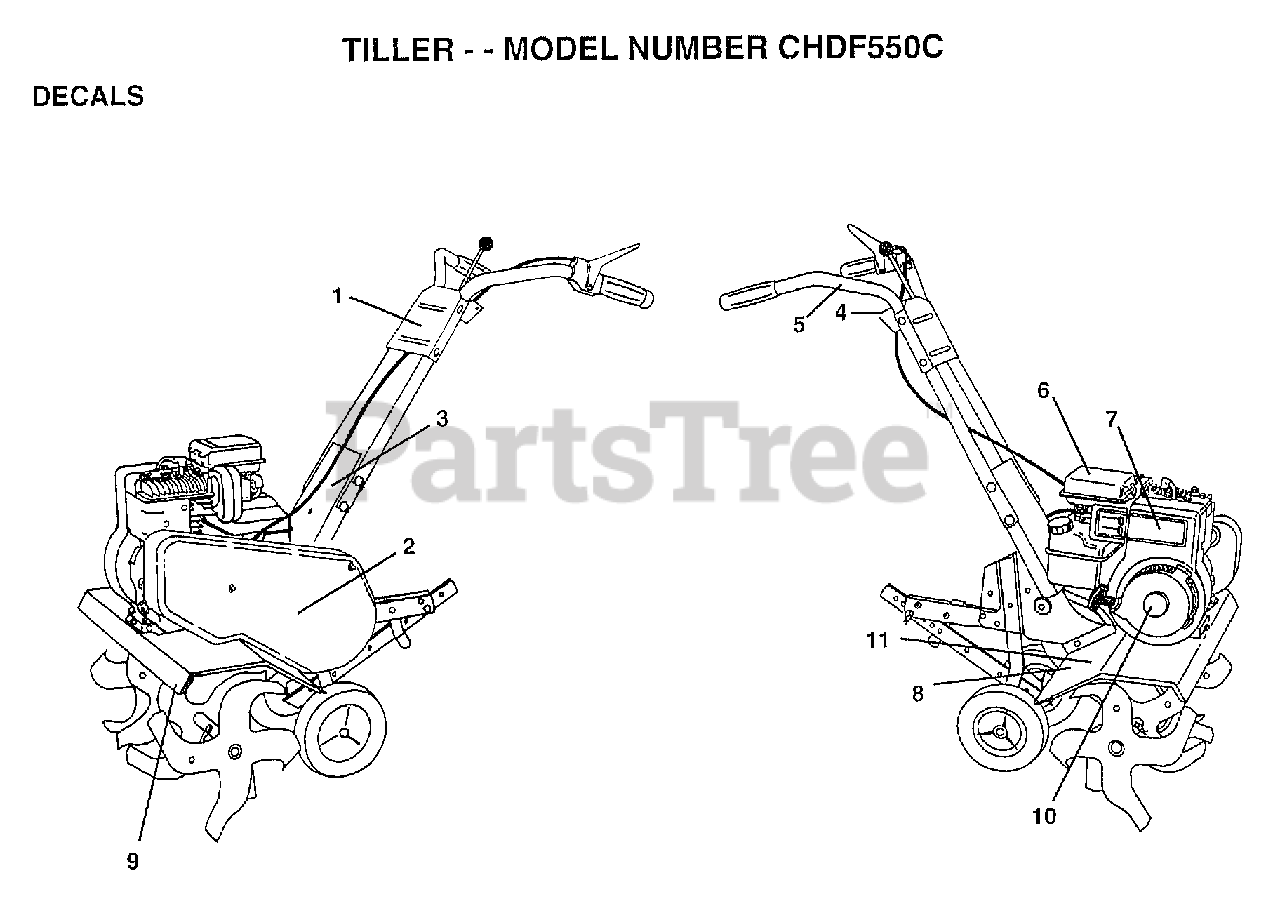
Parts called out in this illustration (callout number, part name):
1	"DECAL PANEL,CTRL"
2	"DECAL GUARD,BELT"
3	"DECAL PANEL,FORWD"
4	DECAL REVERSE
5	DECAL TI
6	DECAL TI
7	DECAL, BRIGGS & STRATTON
9	"DECAL SHIELD,TINE"
11	DECAL.CAUTION
